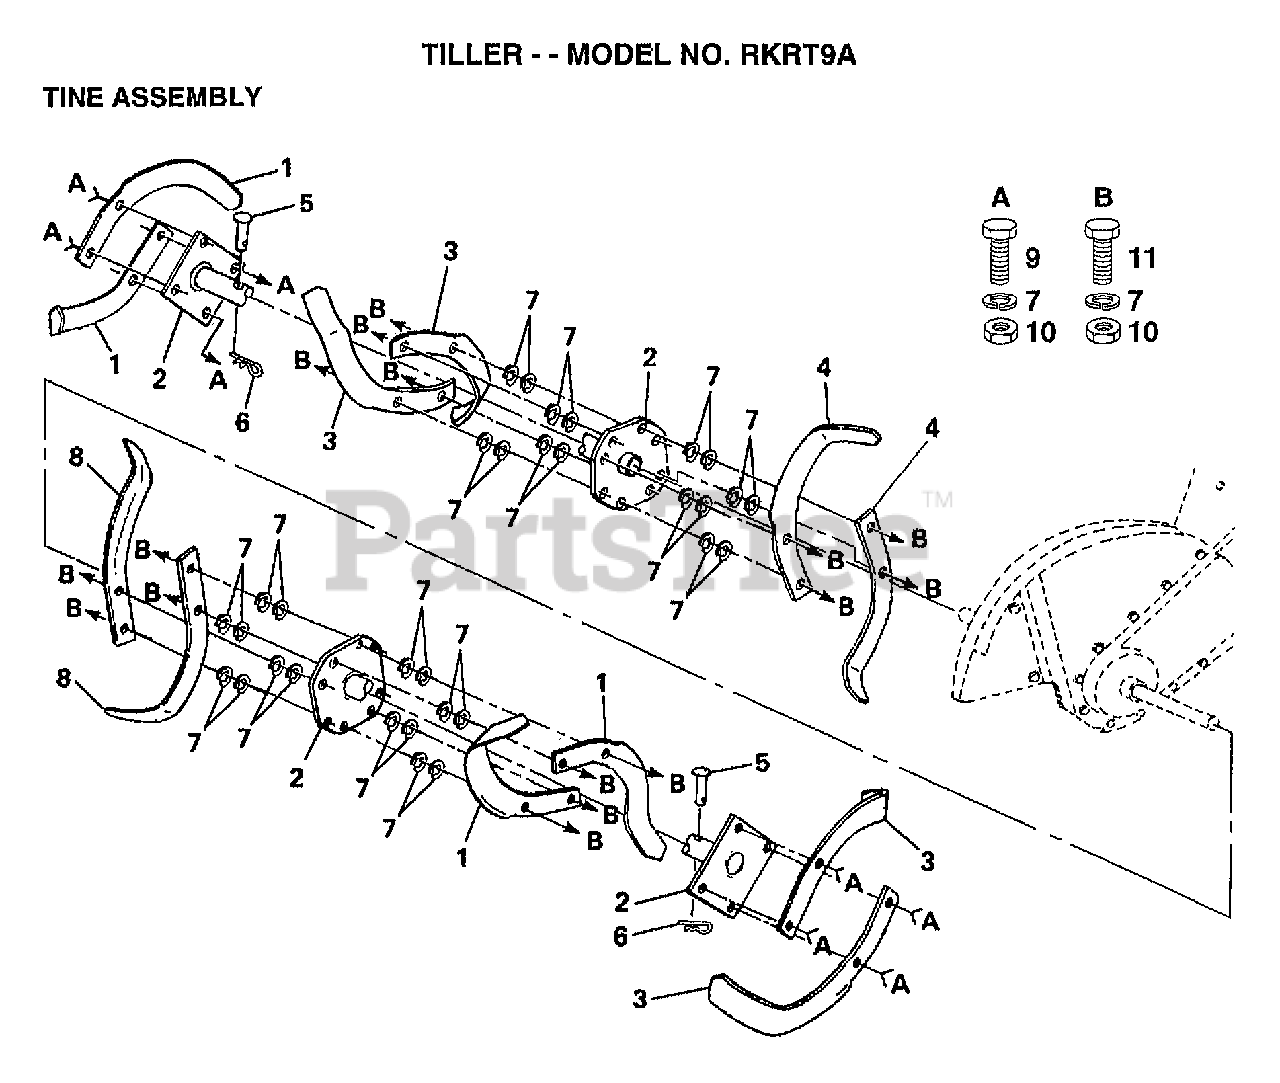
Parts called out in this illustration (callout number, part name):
2	TINE ASSY CRT
4	TINE.LH.CRT
5	RIVET.PAN HD.1.75
6	RETAINER SPRING
7	LOCKWASHER
8	TINE RH CRT
9	BOLT
11	BOLT.3/8-24X1-1/2
